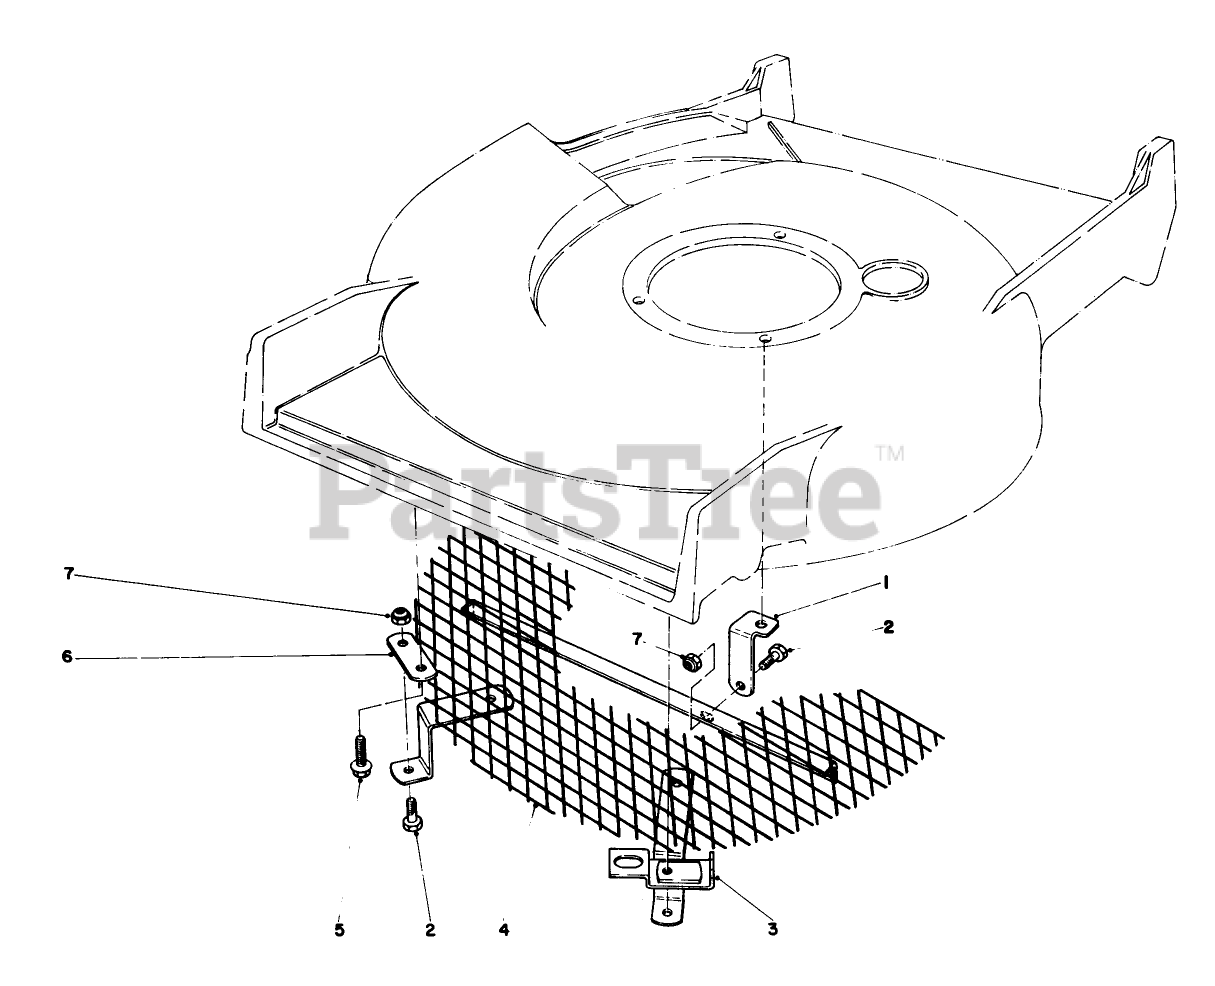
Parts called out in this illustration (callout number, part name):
2	SCREW-HH
3	MTG. BRACKET W.A.
5	SCREW-THD ROLL, HWH
7	NUT-LOCK, NI
